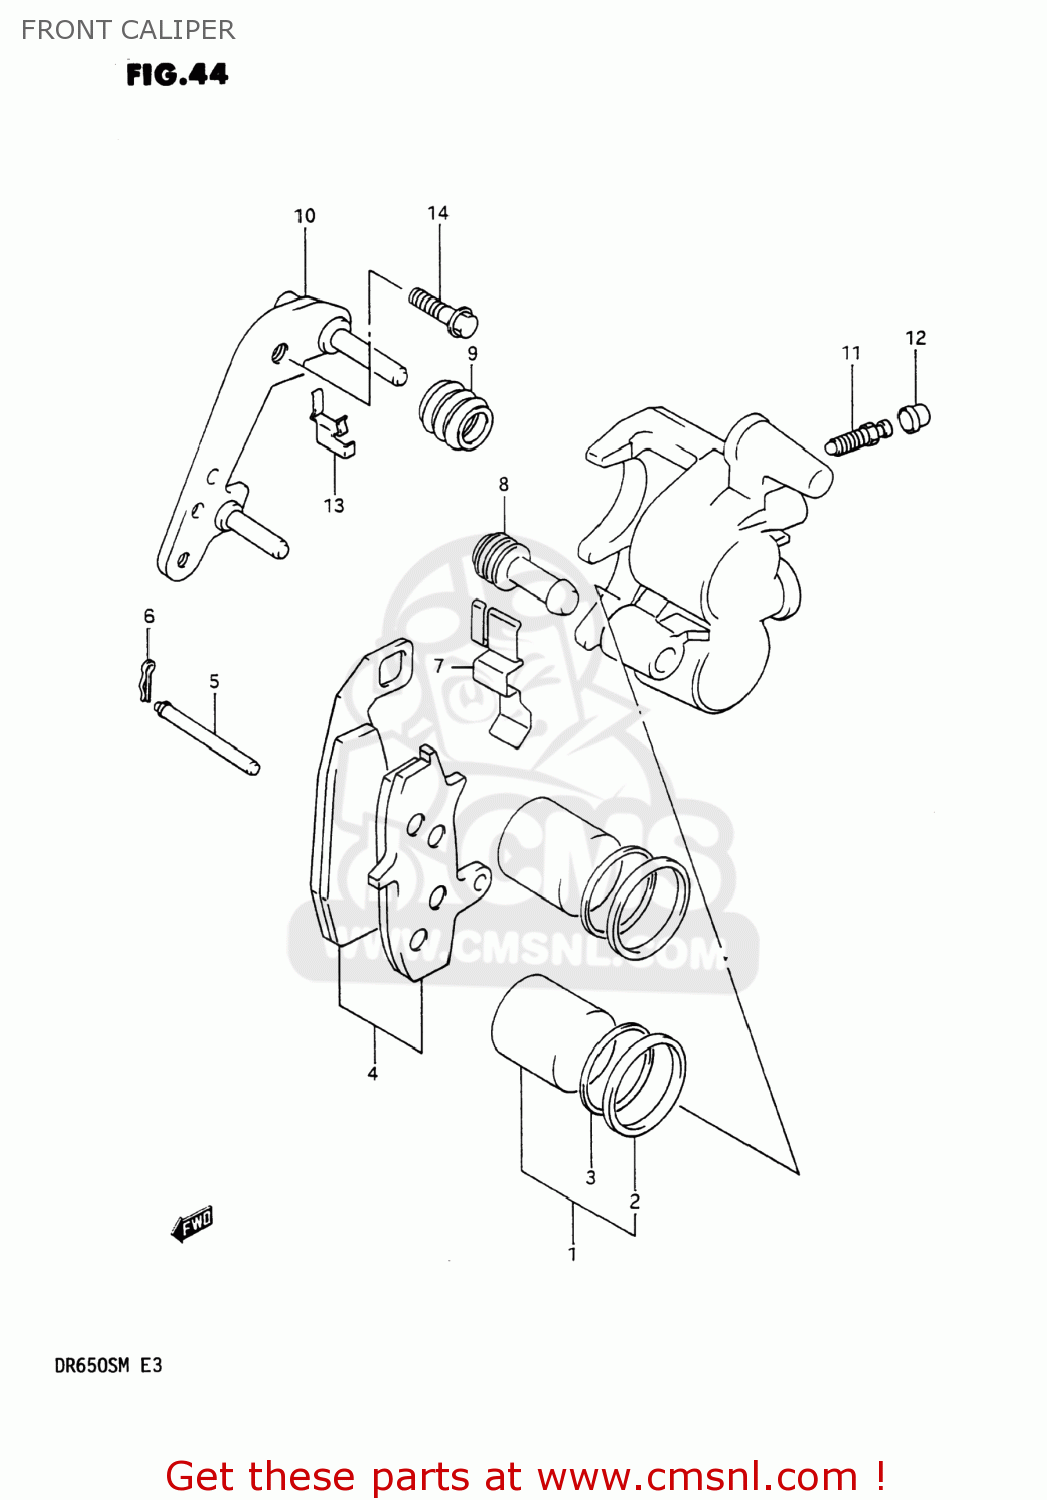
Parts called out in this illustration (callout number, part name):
1	PISTON SET
2	SEAL,PISTON
3	SEAL,WIPER
4	PAD SET (NAS)
5	PIN,PAD
6	CLIP,PAD PIN
7	SPRING,PAD
8	INSULATOR,AXLE
9	BOOT,AXLE
10	BRACKET
11	BLEEDER
12	CAP,BREATHER
13	GUIDE,PAD
14	BOLT
